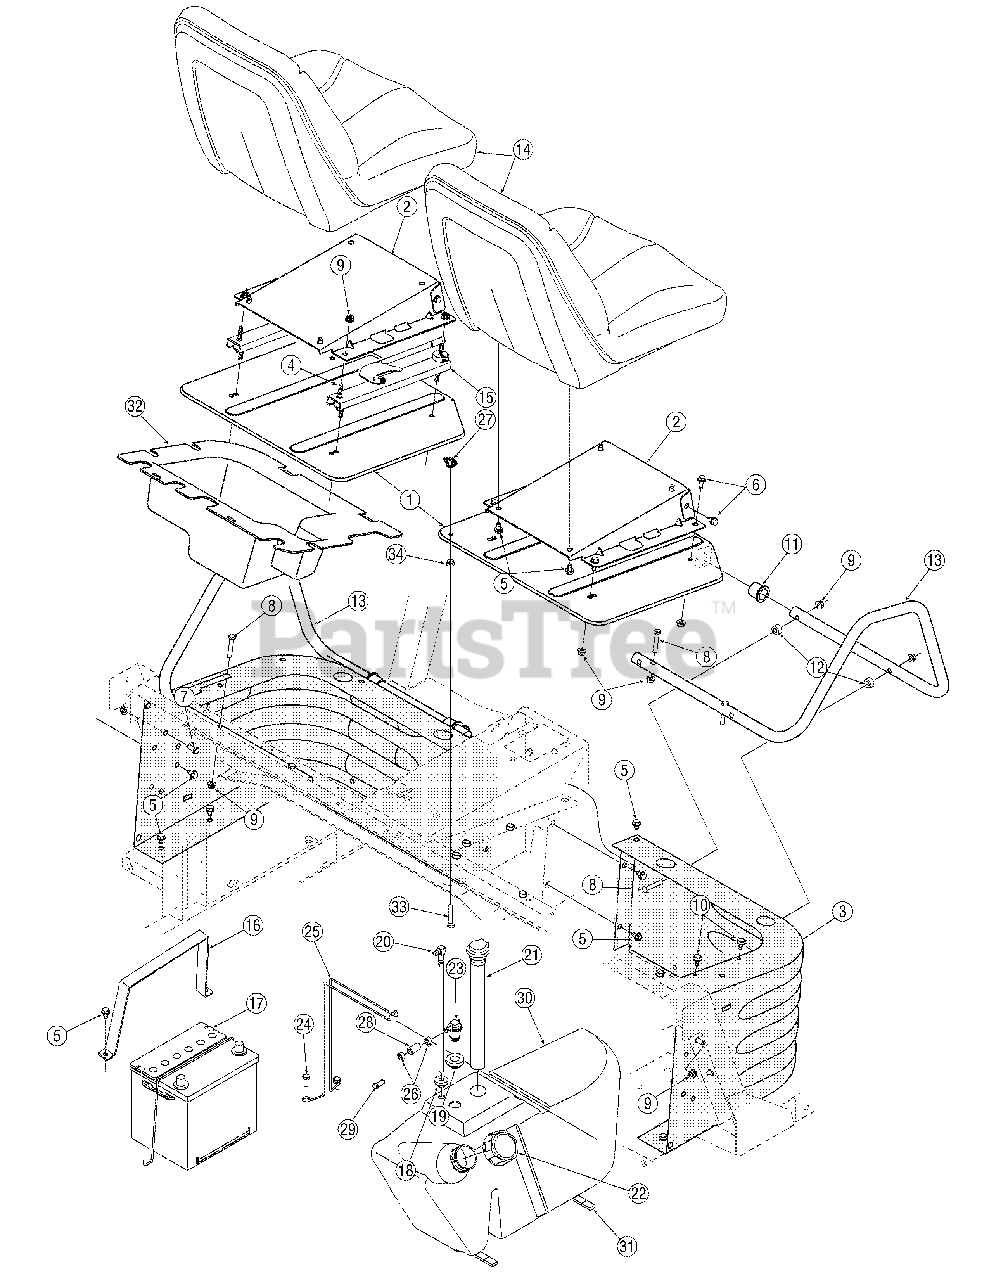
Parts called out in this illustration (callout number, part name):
4	Bolt, Crg., 5/16-18 x .62
5	Scr., TT, 5/16-18 x .500
6	Screw, LD, 5/16-18 x .750
7	Screw, 5/16-18 x .75
8	Screw, 5/16-18 x 1.75
9	Nut, Flglk, 5/16-18
10	Bmpr, .62 Dia. x .3
11	Brg, Flg, .894 ID x 1.1315 OD
12	Spcr, .315 x .750 x .375 Lg.
14	Seat
15	Track, Seat
17	Battery, 540 CCA Dry
18	Bush, Tank, Gas
19	Bush, Tank, Vent
20	Ftg, Fuel, Pickup, 4x4
21	Sensor, Fuel, Low
22	Cap, Fuel Kohler Engine
22	Cap, Fuel Diesel Engine
23	Ftg, Fuel, Vent
24	Screw, 5/16-18 x .500 Kohler Engine
24	Screw, 5/16-18 x .75 Diesel Engine
25	Wire, tank, fuel
26	Clamp, Hose, .490 Dia. Diesel Engine
27	Nut, Wing, 1/4-20
28	Fuel Line, 5/16 Id X .56 Od Kohler Engine
28	Hose, Fuel Line Diesel Engine
29	Vent, 3/8 Dia. Diesel Engine
30	Tank assembly, Fuel Kohler Engine
30	Tank assembly, Fuel Diesel Engine
31	Tape, .625 Wide X.25 Thk Foam
32	Tray, Seat box
33	Screw, 1/4-20 x 1.00
34	Nut, Flange Lock, 1/4-20
